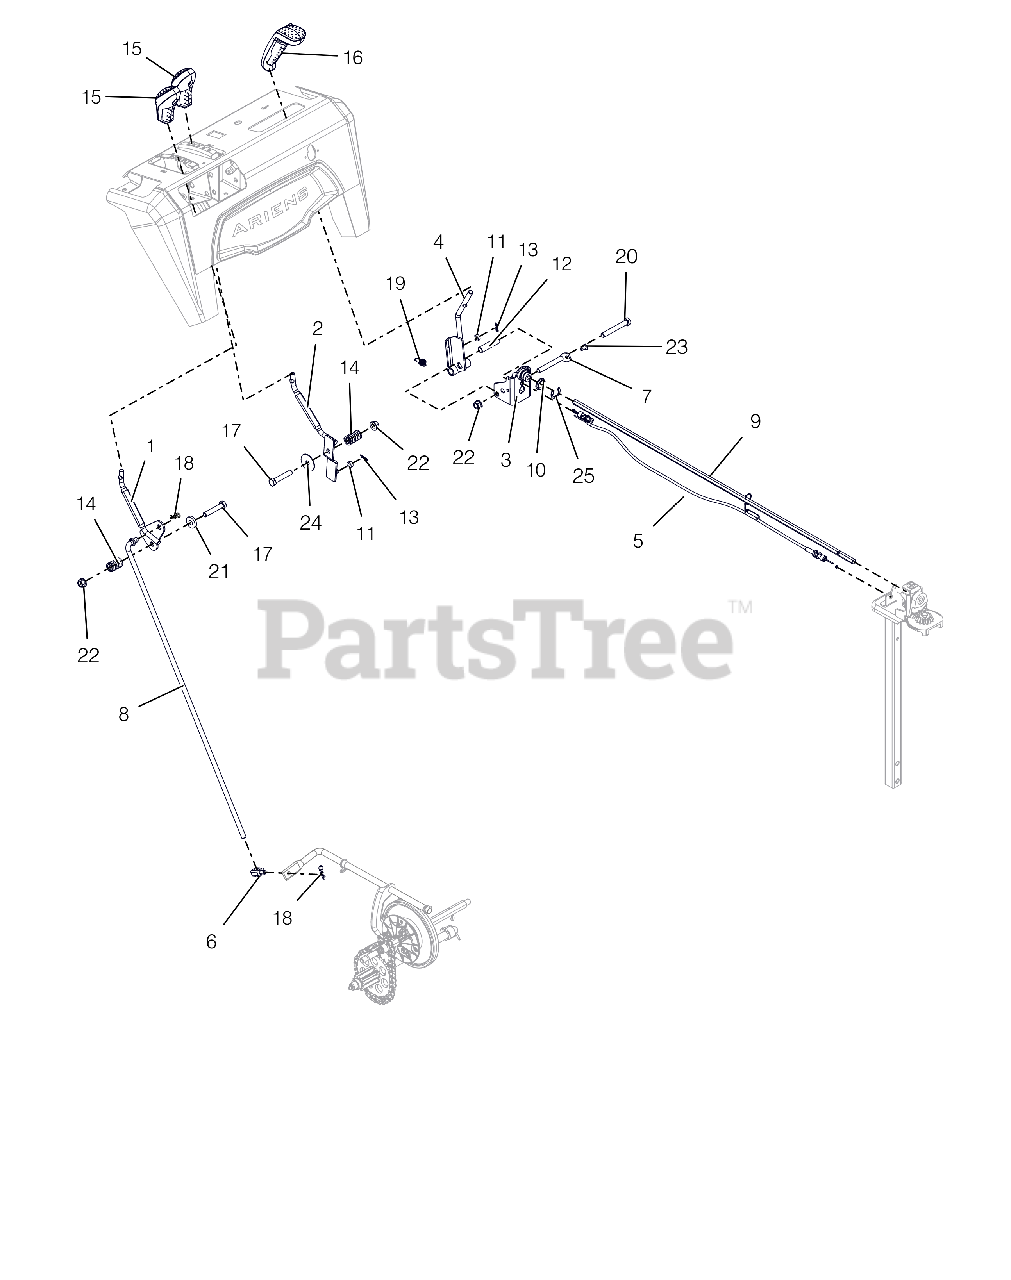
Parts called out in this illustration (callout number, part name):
1	WELDMENT,LG DASH SPEED CONTROL
2	WELDMENT,LG DASH DEFL CONTROL
3	WELDMENT-CONTROL BRACKET-CHUTE
4	WELDMENT,LG DASH QT CONTROL
5	CABLE, CHUTE LOCK, PRO
6	PIVOT,SHIFT ROD .375-16(TRUNN)
7	ROD, PIVOT - INTERLOCK
8	ROD, SHIFT-PRO
9	ROD, HEX - CHUTE ROTATION
10	BUSHING, POLYLINER-.75 SNAPIN
11	BSHG-SLV .265X.500X.219
12	SPCR, WHEEL .385X.500X2.00
13	PIN-HAIR INT .06X.18X.77
14	SG-COMP .125X.781X1.250
15	KNOB, CONTROL, DASH
16	HANDLE, QUICK TURN, ASM
17	@BLT-HEX .38-16X2.00 GR5 YWZC
18	PIN-HAIR INT .08X.18X1.18 YWZC
19	SPRING-EXT .047X.438X1.45
20	@BLT-HEX .38-16X2.75 GR5 YWZC
21	WSHR-FL-STL .406X1.00X.188 YWZ
22	@NUT-LK-TOP-FLG .38-16 YWZC
23	SCR-TAP .25-20X.50 HWH TR YWZ
24	WSHR-FL-STL .380X1.50X.062 YWZ
25	E-RING .750X.050
